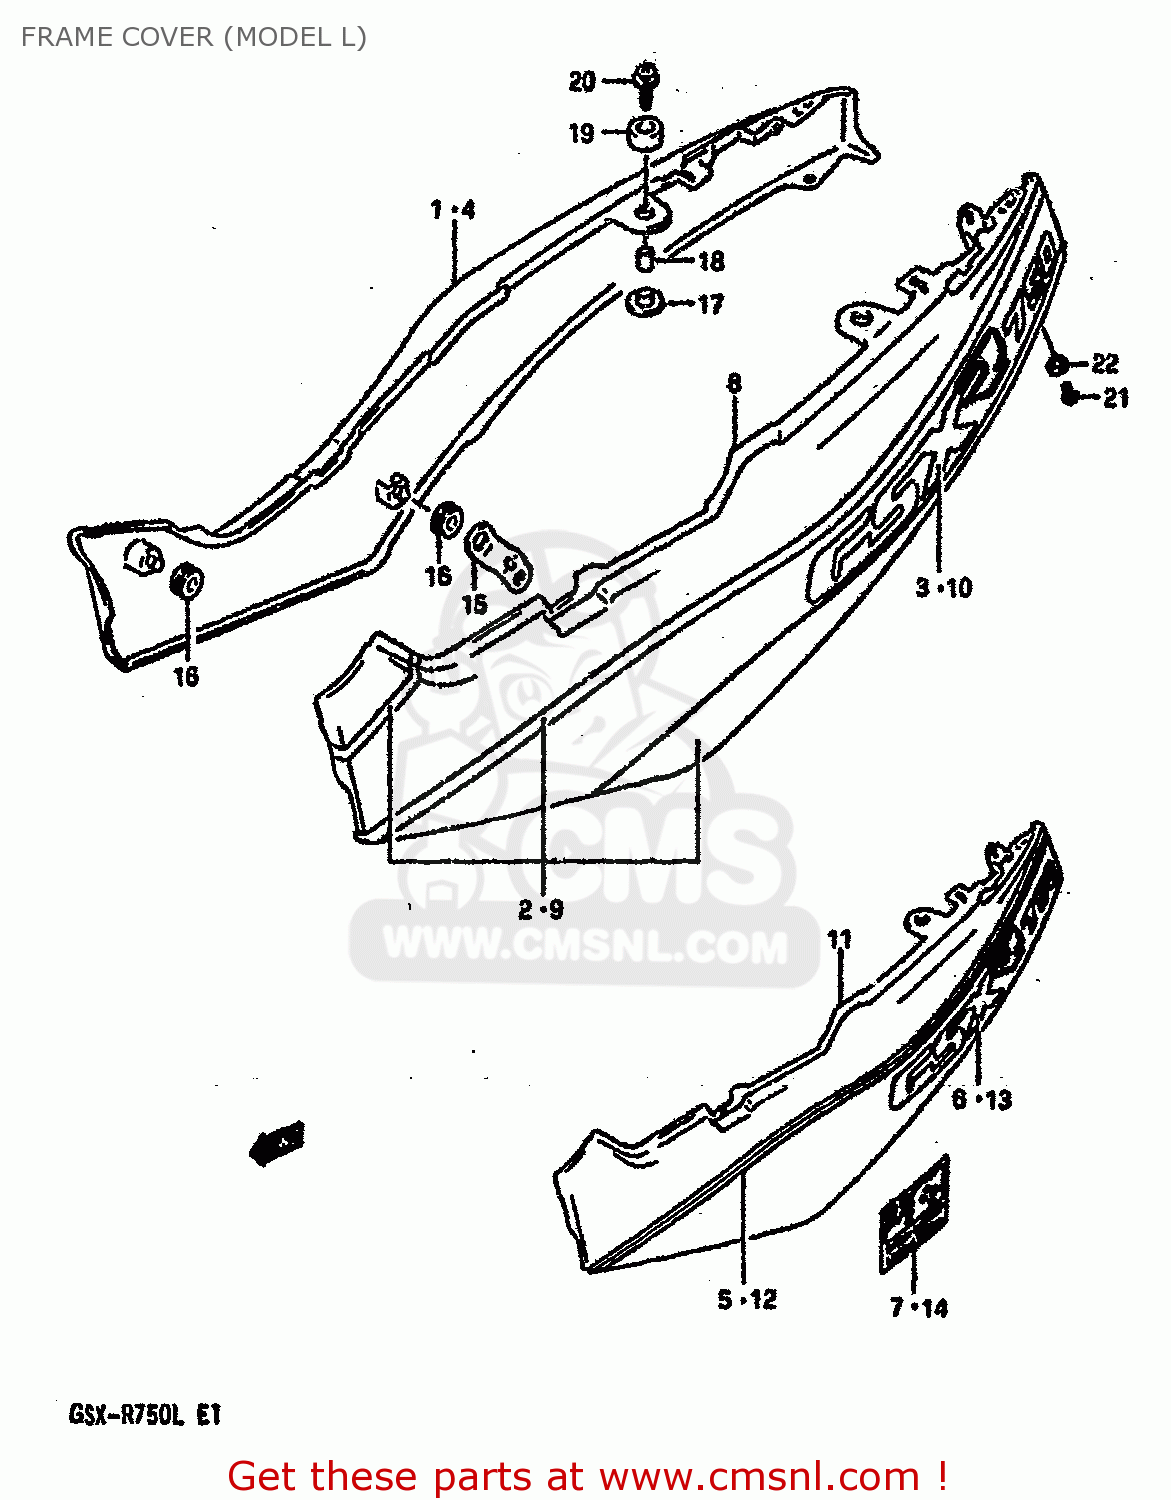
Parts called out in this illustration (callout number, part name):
1	COVER,FRAME,R
2	TAPE SET,FRAME COVER STRIPE
3	EMBLEM,FRAME COVER
4	COVER,FRAME RH
5	TAPE,FRAME COVER STRIPE
6	EMBLEM,FRAME COVER
7	TAPE,FRAME COVER
8	COVER COMP,FRAME,LEFT
9	TAPE SET,FRAME COVER STRIPE
10	EMBLEM,FRAME COVER
11	COVER,FRAME LH
12	TAPE,FRAME COVER STRIPE
13	EMBLEM,FRAME COVER
14	TAPE,FRAME COVER
15	BRACKET,FRAME COVER
16	CUSHION
17	CUSHION,FRAME COVER LWR
18	SPACER
19	CUSHION,TAIL COVER UPR
20	SCREW(6X30)
21	SCREW, FRONT & REAR
22	WASHER(5.2X14X1.5)
23	CUSHION,TAIL COVER UPR
24	SCREW
25	WASHER
26	SCREW, FRONT & REAR
27	WASHER(5.2X14X1.5)
